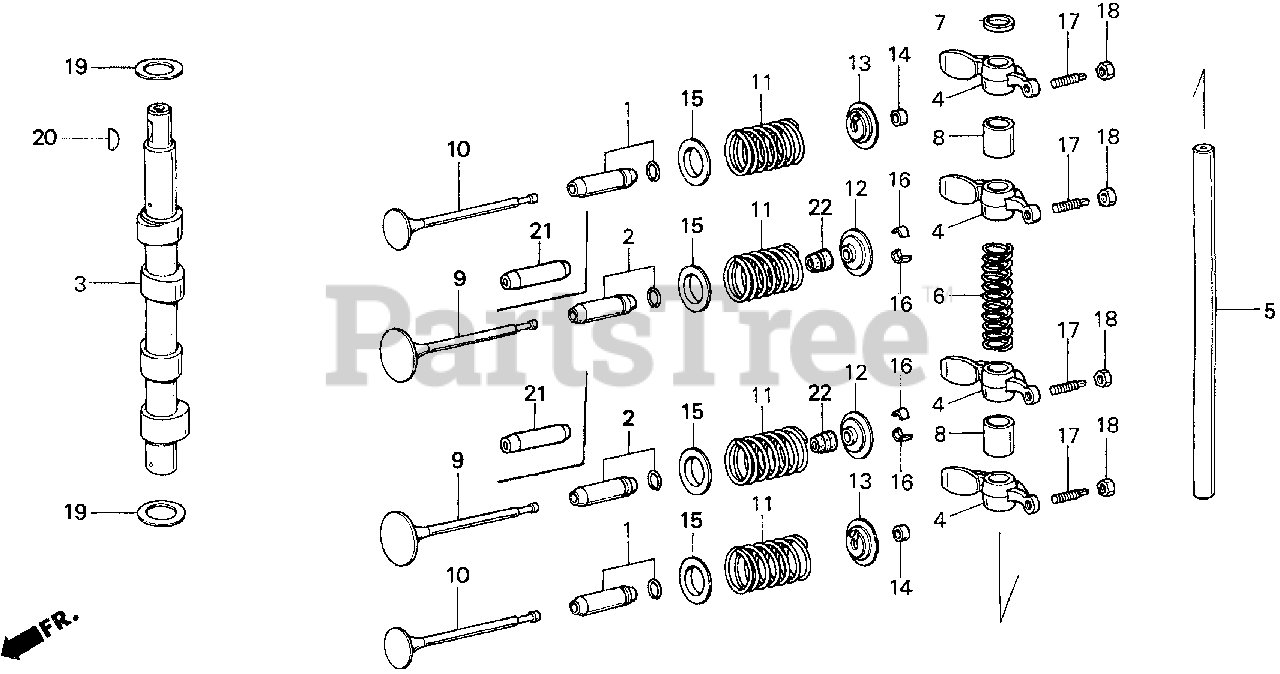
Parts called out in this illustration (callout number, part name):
1	GUIDE, VALVE
2	GUIDE, VALVE (NOT AVAILABLE)
3	CAMSHAFT (NOT AVAILABLE)
4	ARM, VALVE ROCKER
5	SHAFT, VALVE ROCKER ARM
6	SPRING, VALVE ROCKER ARM
7	COLLAR A, VALVE ROCKER ARM
8	COLLAR B, VALVE ROCKER ARM
9	VALVE, IN.
10	VALVE, EX.
11	SPRING, VALVE
12	RETAINER, VALVE SPRING
13	RETAINER, VALVE SPRING
14	ROTATOR, VALVE
15	SEAT, VALVE SPRING
16	COTTER, VALVE
17	SCREW, TAPPET ADJ.
18	NUT, TAPPET ADJ.
19	WASHER, THRUST (16MM)
20	KEY, WOODRUFF (16X12)
